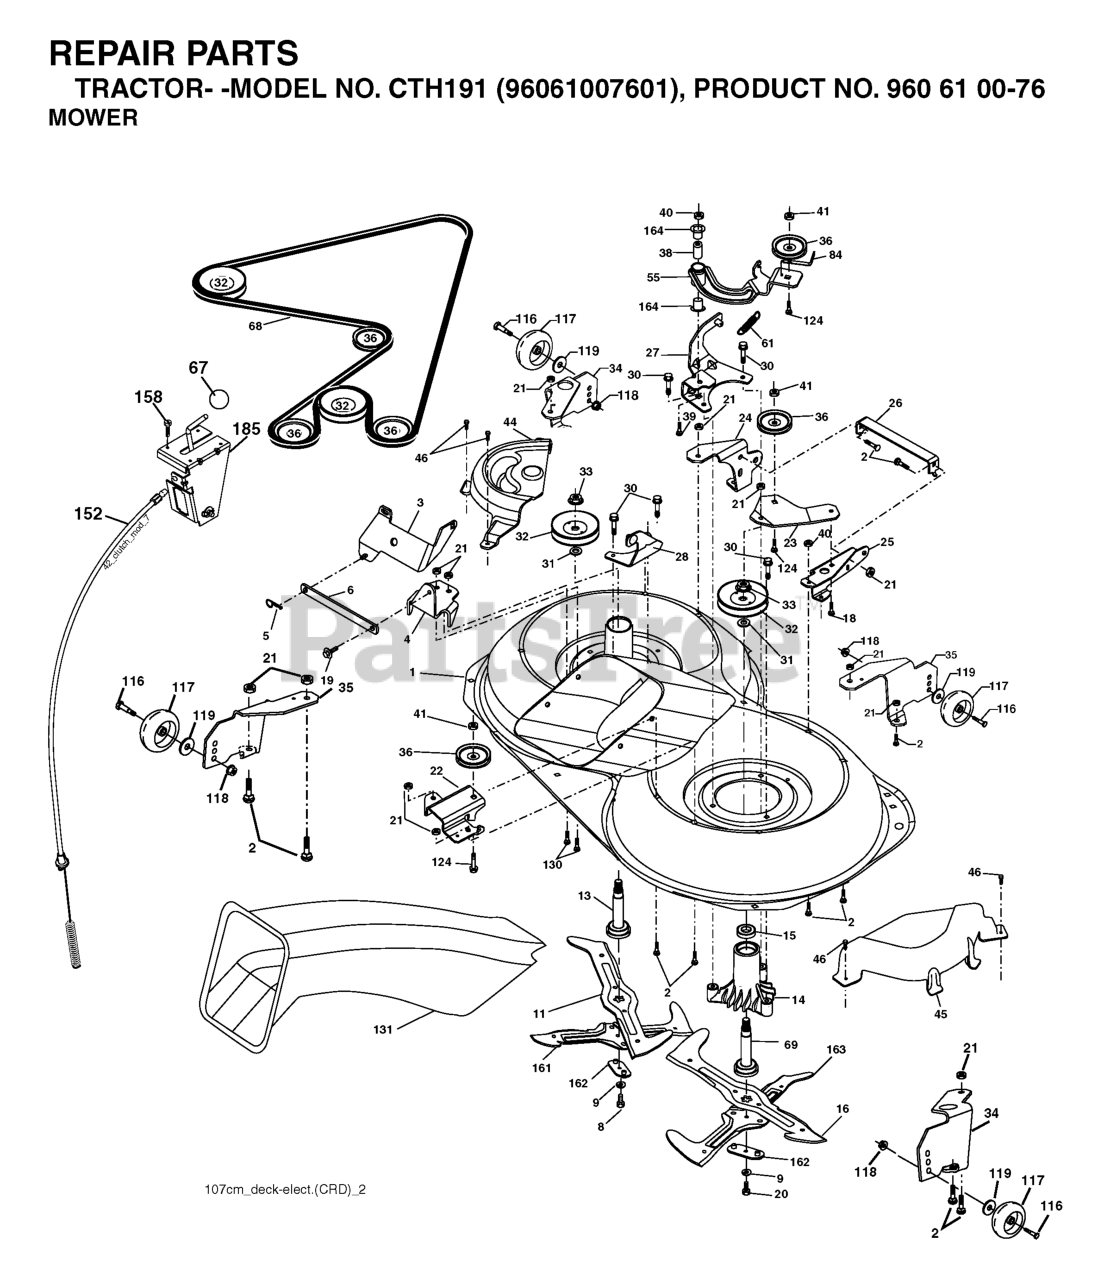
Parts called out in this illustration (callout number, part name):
1	Housing Asm. Mower 107 CRD
2	RP BOLT 5/16-18 X3/4 ZN/YEL GR
5	RETAINER-SPRNG RB
6	BAR.SWAY.92.CRD
8	BOLT.3/8-24X1.25 GR8
9	LOCKWASHER
11	BLADE.3N1.LH.CRD
13	SHAFT ASM VENT
14	HOUSING.MANDREL.VENTED (MACHD)
16	BLADE.3N1.RH.CRD
18	BOLT
19	BOLT SHD 5/16-18
20	BOLT.3/8-24X1.25GR8. LHTHRD
21	LOCKNUT
22	BRACKET.IDLER.RR.107.CRD
25	BRACKET RF
26	SUPPORT
28	BRACKET
30	SCREW, WASHER HEAD
31	WASHER.SPACER.MANDREL
33	NUT.FLANGE.LOCK.TOP
34	BRACKET
35	BRACKET
36	PULLEY.IDLER.4.25
41	NUT LOCK FLG 3/8-16 UNC
45	COVER.MANDREL.RH.CRD
46	SCREW.1/4-20X5/8
55	ARM.IDLER.107.CRD
67	KNOB T (3/8 HOLE)
68	HEX-BELT 107 MOWER
69	SHAFT.ASM.W/LWR.BRG.RH.THREAD
84	KEEPER, BELT IDLER
116	SHOULDER BOLT
117	RP WHEEL. GUAGE RALLY
118	LOCKNUT
119	WASHER.5/16.FLAT.STE.STD.
124	BOLT.3/8-16X1.50
130	BOLT.CARR.SQNK.5/16-18UNC.X3/4
131	CHUTE BAGGER
158	SCREW
163	BLADE.CROSS.RH.CRD.107
164	BRNG T
185	HEAD ASM. CABLE CLUTCH
